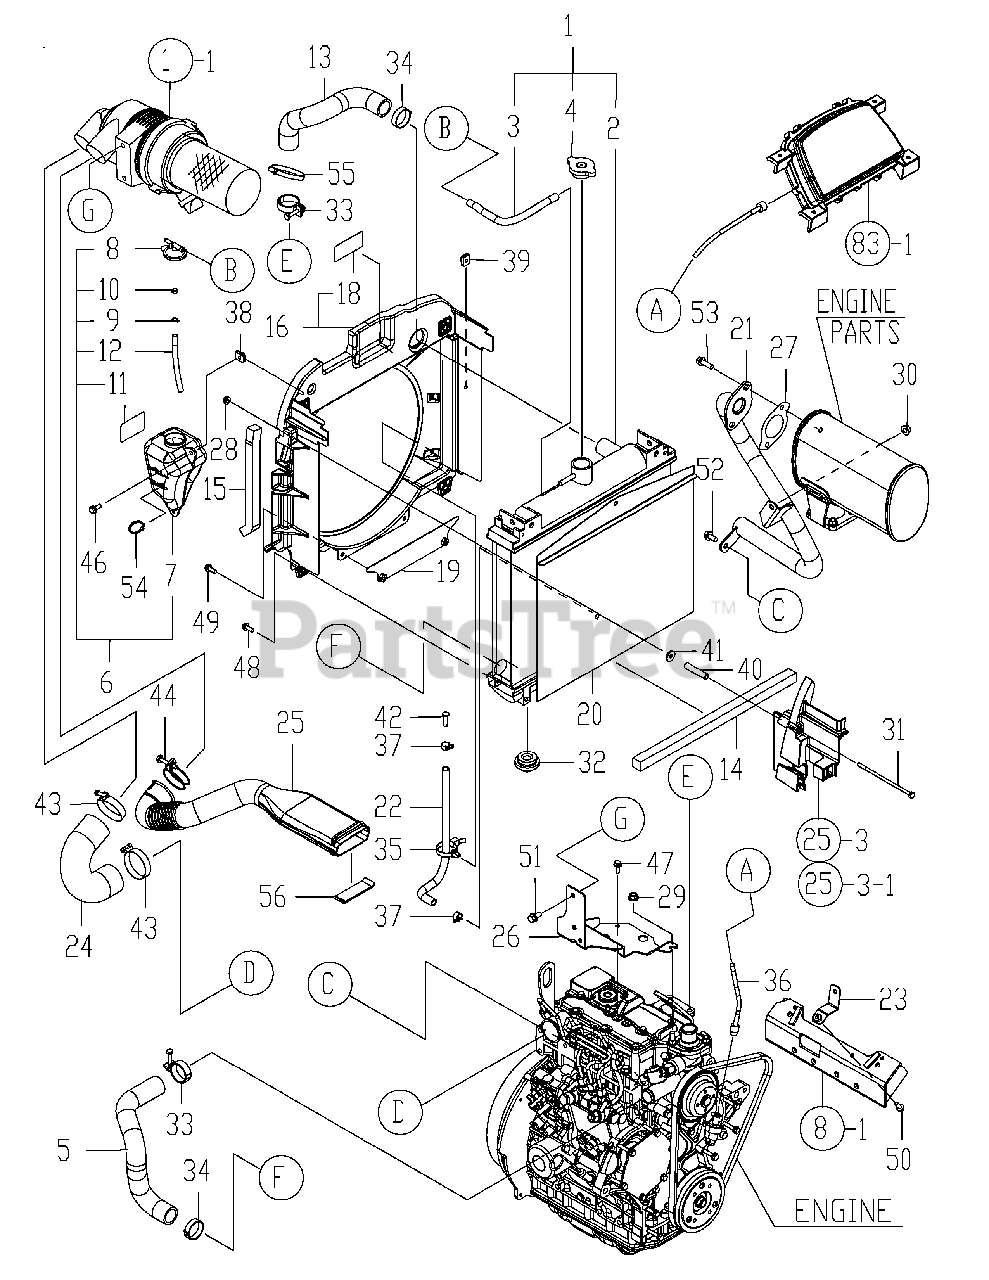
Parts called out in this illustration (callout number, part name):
2	RADIATOR
5	PIPE, WATER 66
6	TANK ASSY,COOLANT
7	TANK,COOLANT
9	RETAINER, PIPE
11	LABEL-OVERFLOW TANK
13	HOSE, COOLING WATER
15	SEAL,SHROUD LOWER
16	SHROUDM ASSY,FAN
18	LABEL,WARNING,FAN
19	PLATE ASSY,SHROUD
20	SCREEN,RADIATOR
24	HOSE,AIR INTAKE
25	AIR INTAKE PIPE
26	BRACKET,AIR CLEANER
27	GASKET, EXHAUST
32	RUBBER, RADIATOR
33	BAND, HOSE 38
34	CLIP, HOSE 31.0
36	CABLE, HOUR METER
37	CLAMP, HOSE 12
40	COLLER, 6.5X10X52
43	CLAMP, HOSE 54
44	CLAMP, HOSE 50
54	CLAMP, WIRE
56	SEAL-AIR INTAKE PIPE
